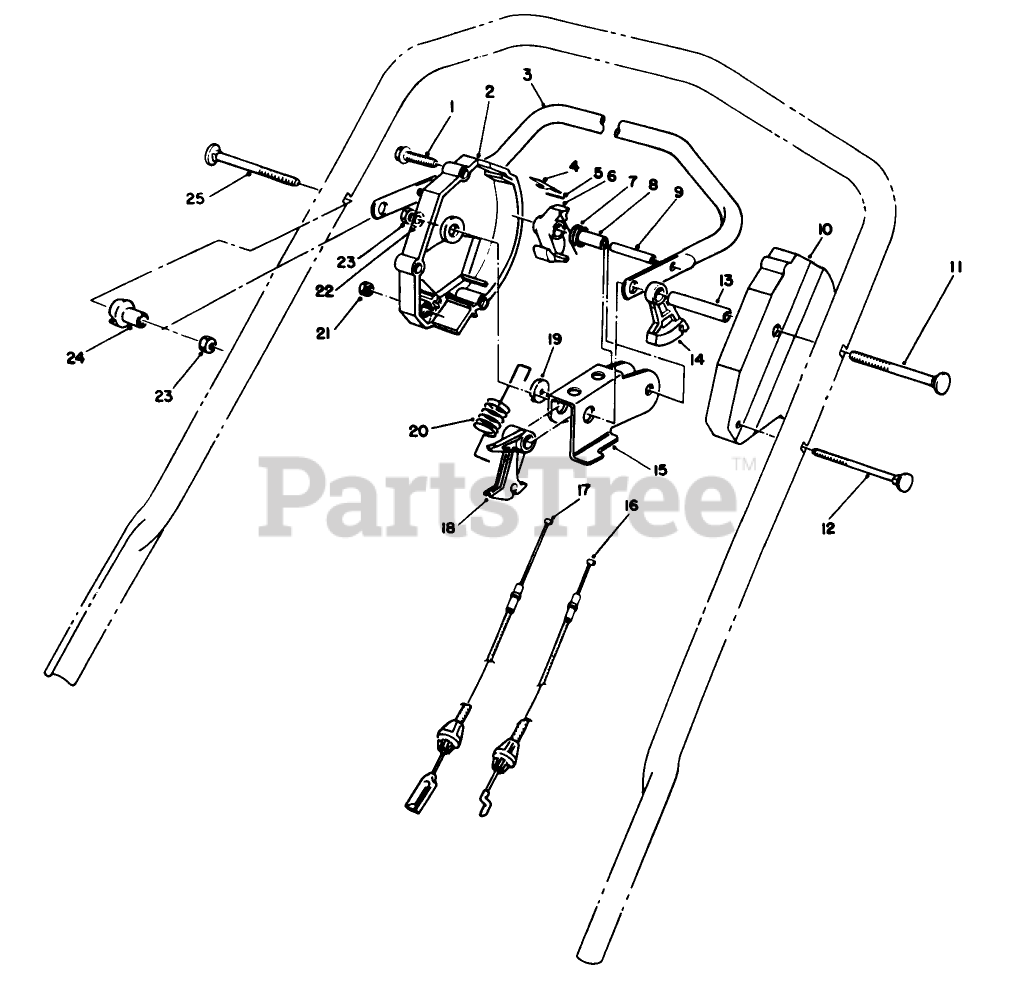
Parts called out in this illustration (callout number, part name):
1	SCREW-HWHTF
4	SPRING-LEAF
5	PIN-INSERT
6	HOOK-CONTROL
7	SPRING-TORSION
8	SPACER
9	PIN-ROLL, SLOTTED
12	HANDLE SCREW
13	TUBING-SPACER
14	LEVER-TRACTION
16	TRACTION CABLE
17	BBC CABLE ASSEMBLY
18	LEVER-CABLE
19	WASHER-NYLON
20	SPRING-DETENT
21	NUT-HEX
22	WASHER-PLAIN
23	NUT-LOCK, NI
24	SPACER-SUPPORT
25	SCREW-HANDLE
